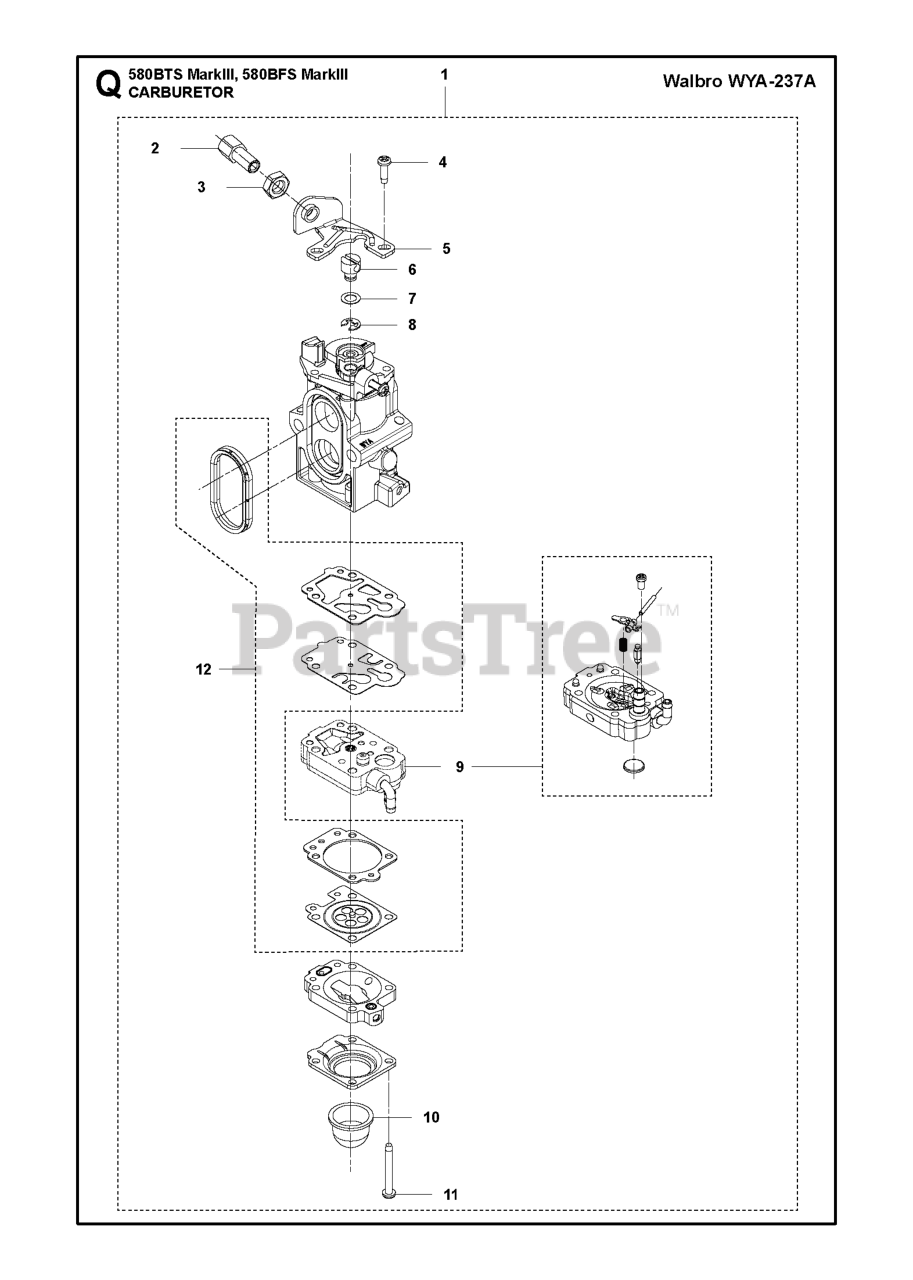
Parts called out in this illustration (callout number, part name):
1	CARBURETOR ASSY
2	SCREW (RPLS 191881170)
3	NUT
9	BODY-A-PUMP
12	GASKET KIT
